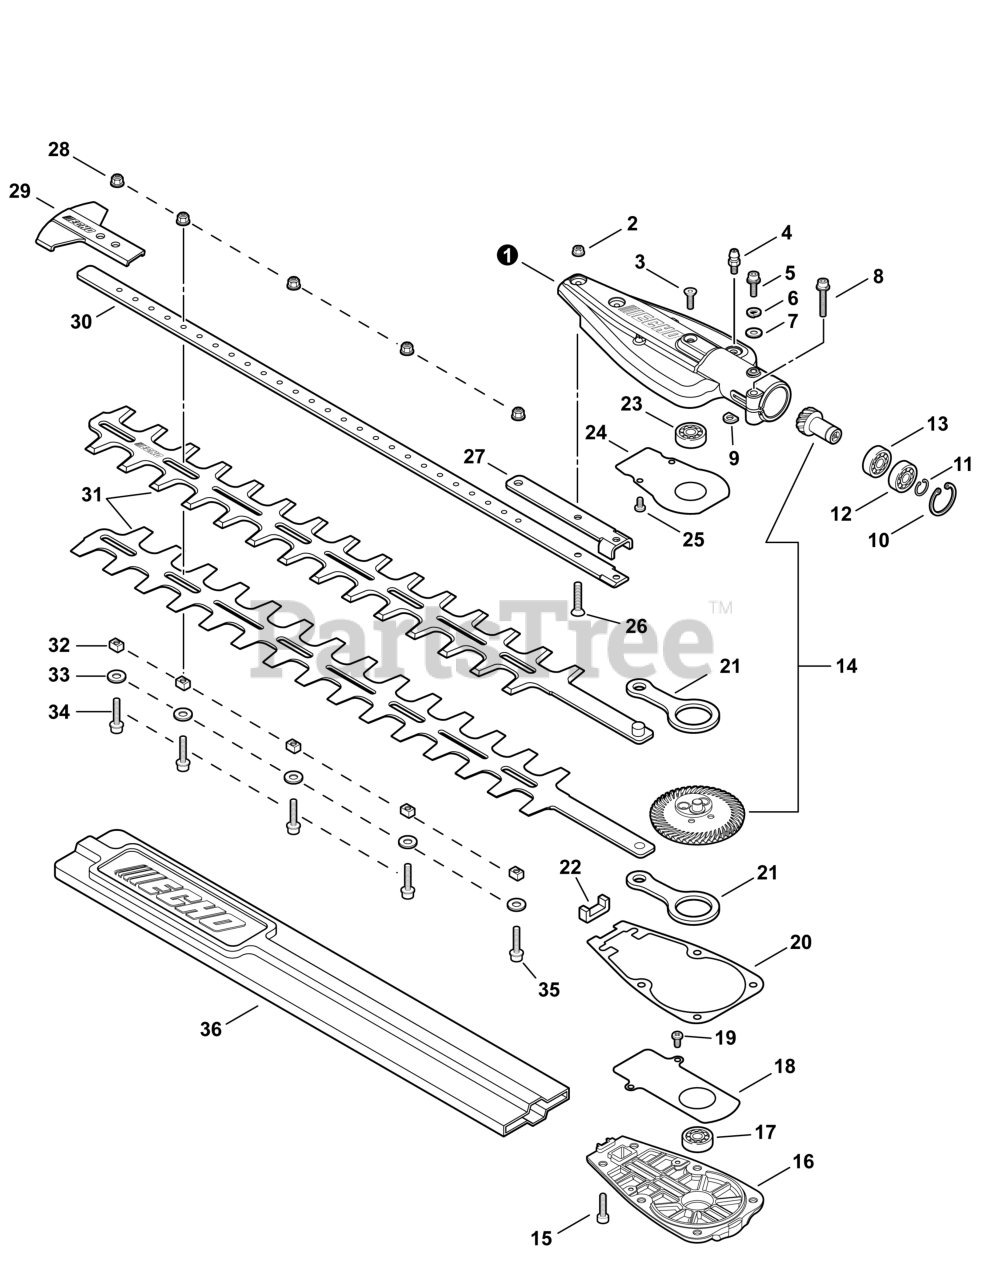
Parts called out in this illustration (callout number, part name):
1	HOUSING, GEAR CASE
2	NUT, FLANGE M5
3	SCREW 5x5/8" HD-SOCKET
4	FITTING, GREASE
5	BOLT, TORX 5x12
6	WASHER, SPRING 5
7	WASHER, FLAT 5.5x10x0.8
8	BOLT, TORX 5x25
9	D-WASHER
10	RING, RETAINING 24
11	RING, SNAP 12
12	BEARING, BALL
13	BEARING, BALL
14	GEAR SET, BEVEL
15	BOLT 5x12
16	COVER, GEAR CASE
17	BEARING, BALL 628ZZ
18	PLATE, WEAR
19	SCREW 4x5
20	GASKET, GEAR CASE
21	ROD, CONNECTING
23	BEARING, BALL 608ZZ
24	PLATE, WEAR
25	SCREW 4x5
26	SCREW 5x18
27	SUPPORT, BLADE
28	NUT, FLANGE M5
29	GUARD, TIP
30	SUPPORT, BLADE
32	GUIDE, BLADE 5
33	WASHER 5
34	BOLT 5x20
35	BOLT, FLANGE 5x22
36	SCABBARD
